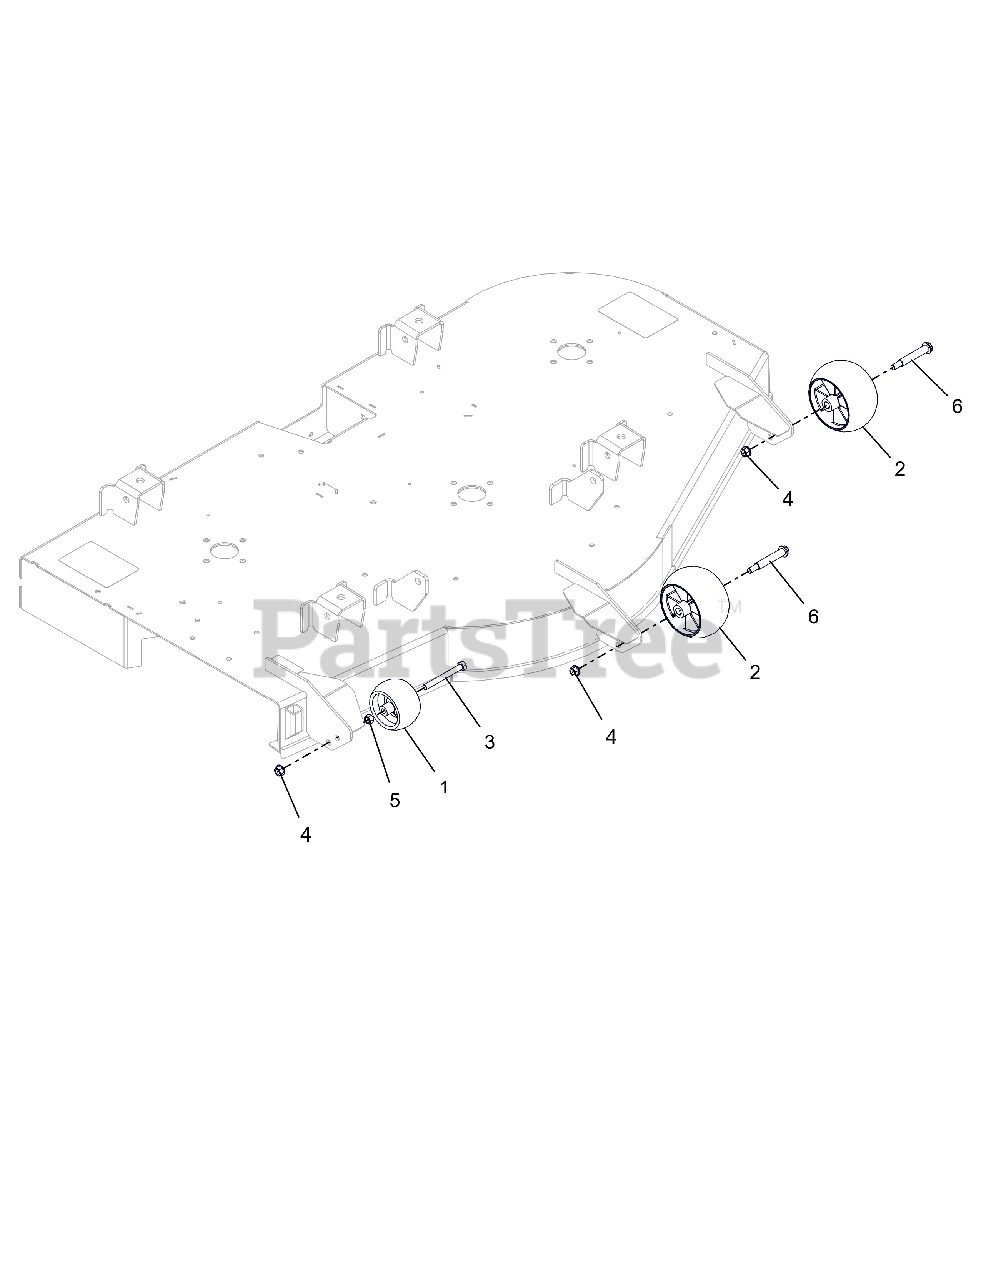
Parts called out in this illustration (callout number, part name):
2	ANTI-SCALP WHEEL - 5X OS
3	BLT, HEX .38-16X3.50 G5 ZCC
4	NUT-LK-TOP-FLG .38-16 ZC120
5	@NUT-HEX .38-16 YWZC
6	BLT-SHLDR .38-16X2.50 HWH G5
